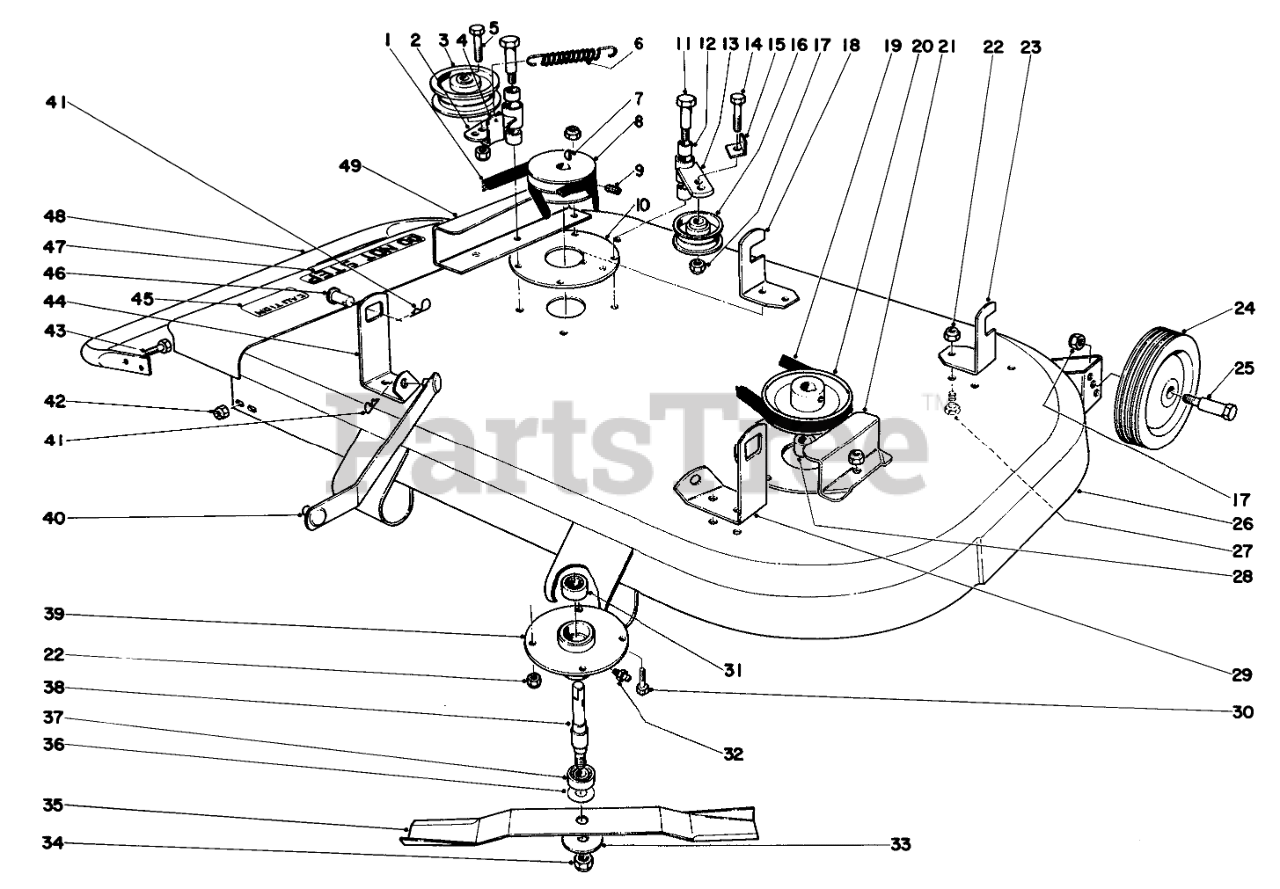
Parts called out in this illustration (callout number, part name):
1	Belt
2	Idler Plate Incl. Ref. #11
3	Idler Pulley
4	belt Retainer
5	SCREW-HH
6	Spring Tension
7	KEY-WOODRUFF
8	BLD SPDLE PULLEY (MACH)
9	SCREW-SET, HSH
10	Washer
11	SHOULDER BOLT
12	BUSHING
13	Idler Plate
14	SCREW-HH
16	PULLEY-IDLER
17	NUT-LOCK, CONE
18	Bracket
20	Pulley
21	Belt Guard
22	NUT-LOCK, CONE
23	Bracket Mower
24	Wheel
26	Housing
27	SCREW-HH
28	Spacer
29	Bracket-Mower
30	SCREW-HH
31	Bearing
32	FITTING-GREASE
33	WASHER
34	NUT-LOCK, CONE
35	Blade
36	WASHER
37	.6693 RP BALL BEARING
38	Blade Spindle
39	MOWER SPINDLE HOUSING
40	Tow Bar
41	PIN-COTTER
42	NUT-LOCK, CONE
43	SCREW-CARR
44	Bracket-Mower
45	Decal
47	Decal
48	Mower Guard
49	Guard Mower
